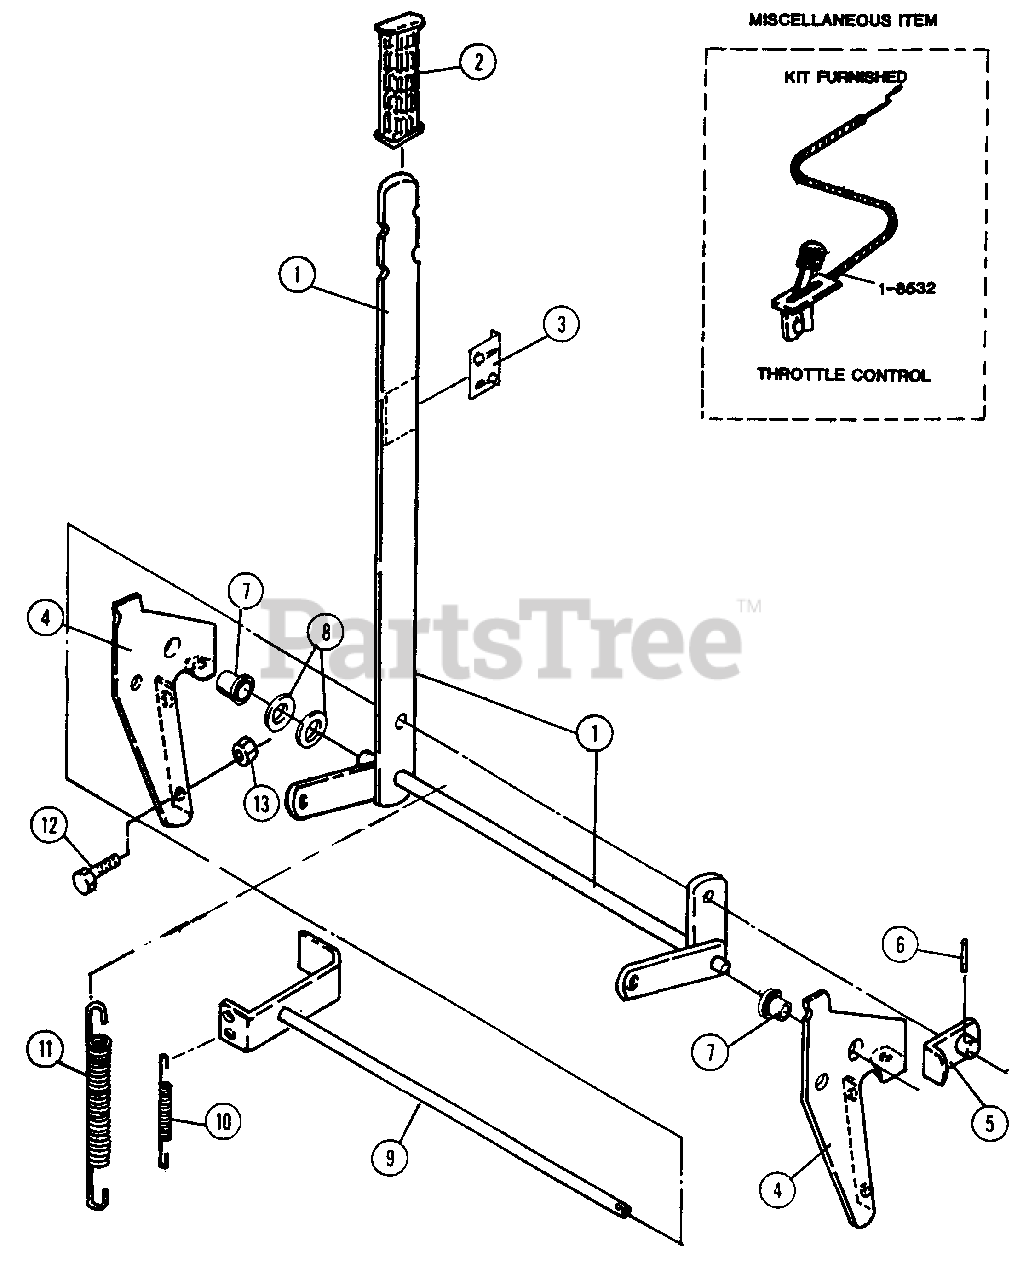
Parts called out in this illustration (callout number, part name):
1	LIFT HANDLE
2	GRIP
3	DECAL, Lift Handle
4	BRACKET, Lift Mounting
5	LATCH
6	ROLL-PIN
7	BUSHING
8	WASHER
9	SHAFT, Lift
10	SPRING, Latch
11	SPRING, Lift Assist
12	SCREW, 5/16-18 x 5/8 Hex Head Cap
13	LOCKNUT, 5/16-18
18532	CONTROL, Throttle
